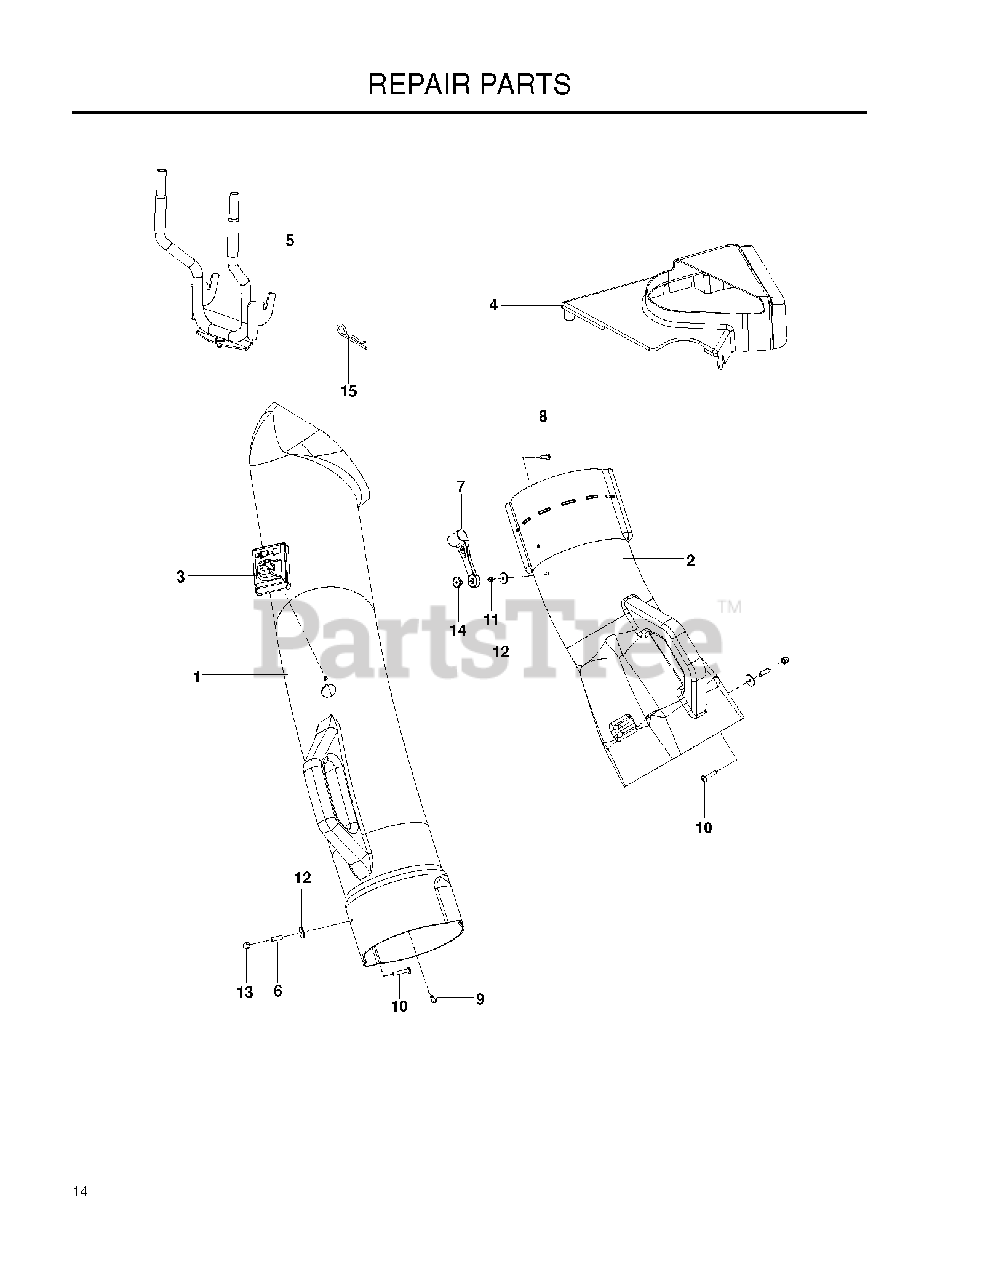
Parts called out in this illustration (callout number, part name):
1	CHUTE, UPPER - TRIMMED
2	CHUTE, MIDDLE
3	DUMP BAG INDICATOR
4	Belt Shield, 52
5	BAGGER.ASM.SUPPORT.GT.TEX.BLAC
6	BSHG .202X.75 LG SPLIT ZD SPEC
7	HOOD LATCH
8	SCREW #10-24 X 5/8
9	SCREW
10	SCREW #10-24 X 1-1/8 ZD SPEC
11	WASHER - 3/16 LOCK ZD
13	NUT 10-24 ACORN ZD
14	NUT 10-24 WELD PLATED
15	HAIRPIN #4
